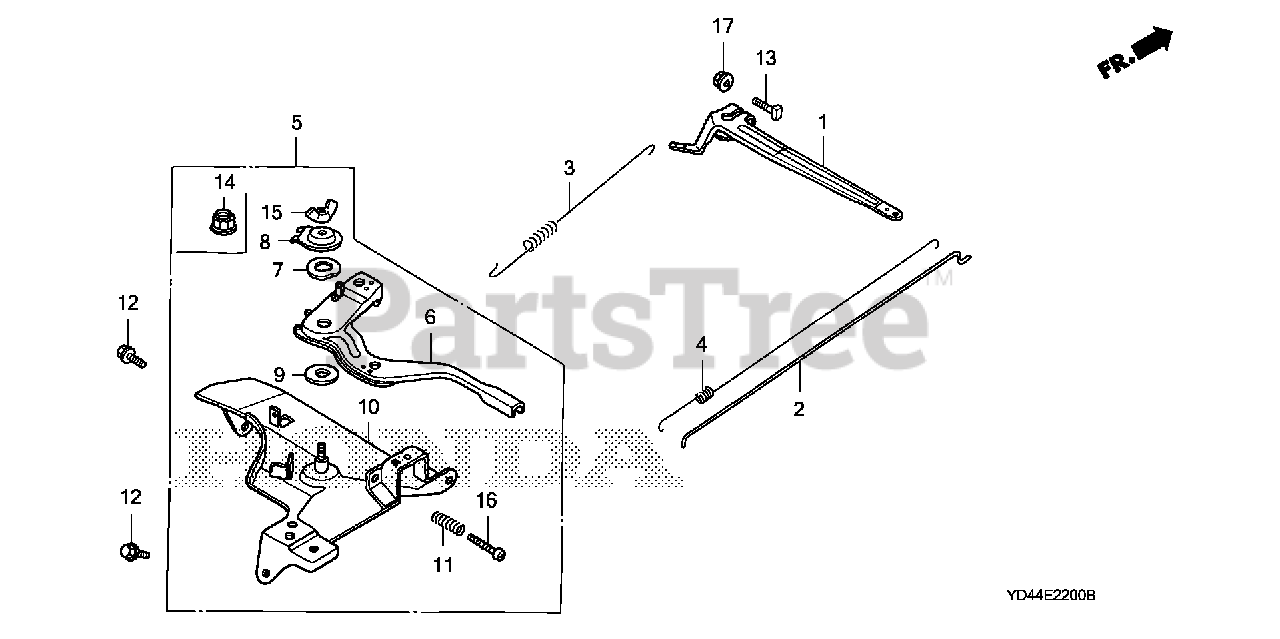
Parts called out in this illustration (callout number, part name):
1	ARM, GOVERNOR
2	ROD, GOVERNOR (STD)
3	SPRING, GOVERNOR (L=137.5MM)
4	SPRING, THROTTLE RETURN
5	CONTROL ASSY. (STD)
6	LEVER, CONTROL
7	SPRING, LEVER
8	WASHER, CONTROL LEVER
9	SPACER, CONTROL LEVER
10	BASE, CONTROL
11	SPRING, CONTROL ADJUSTING
12	BOLT, FLANGE (6X12) (CT200)
13	BOLT, GOVERNOR ARM
14	NUT, SELF-LOCK (6MM)
16	SCREW, PAN (5X32)
17	NUT, FLANGE (6MM)
